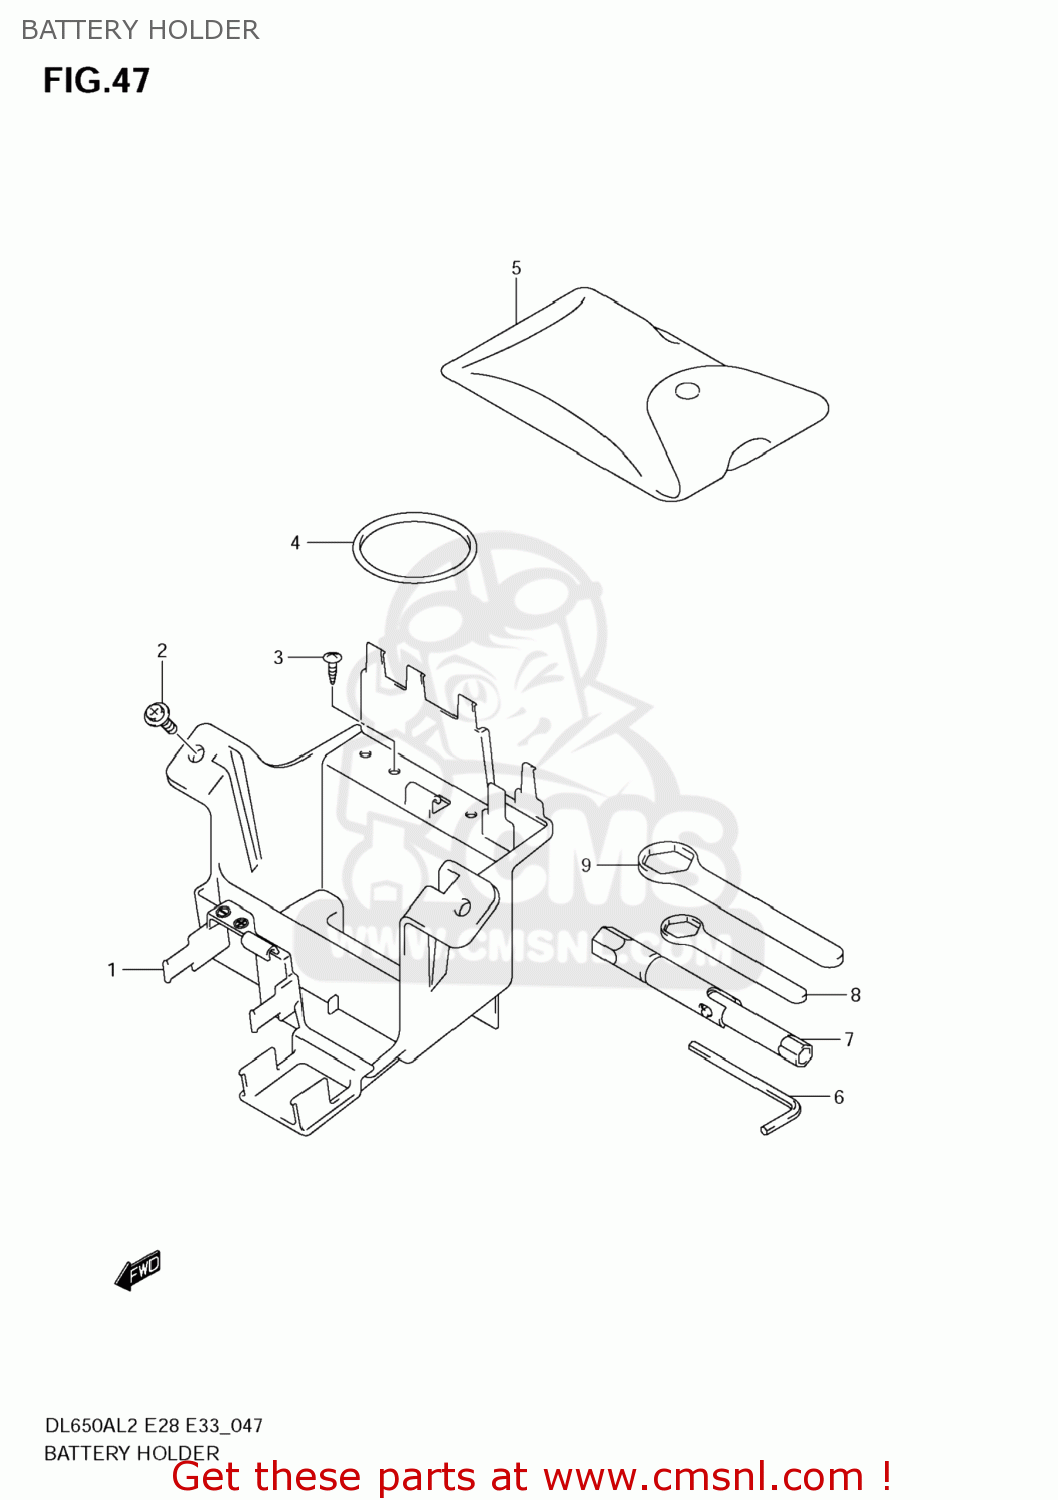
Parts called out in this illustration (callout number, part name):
1	HOLDER,BATTERY
2	BOLT(6X12)
3	SCREW(5X16)
4	O RING(D:3.5,ID:62.6)
5	TOOL ASSY
6	HEXAGON SPANNER,5
7	SPARK PLUG WRENCH
8	RING SPANNER(22)
9	RING,SPANNER(24)
